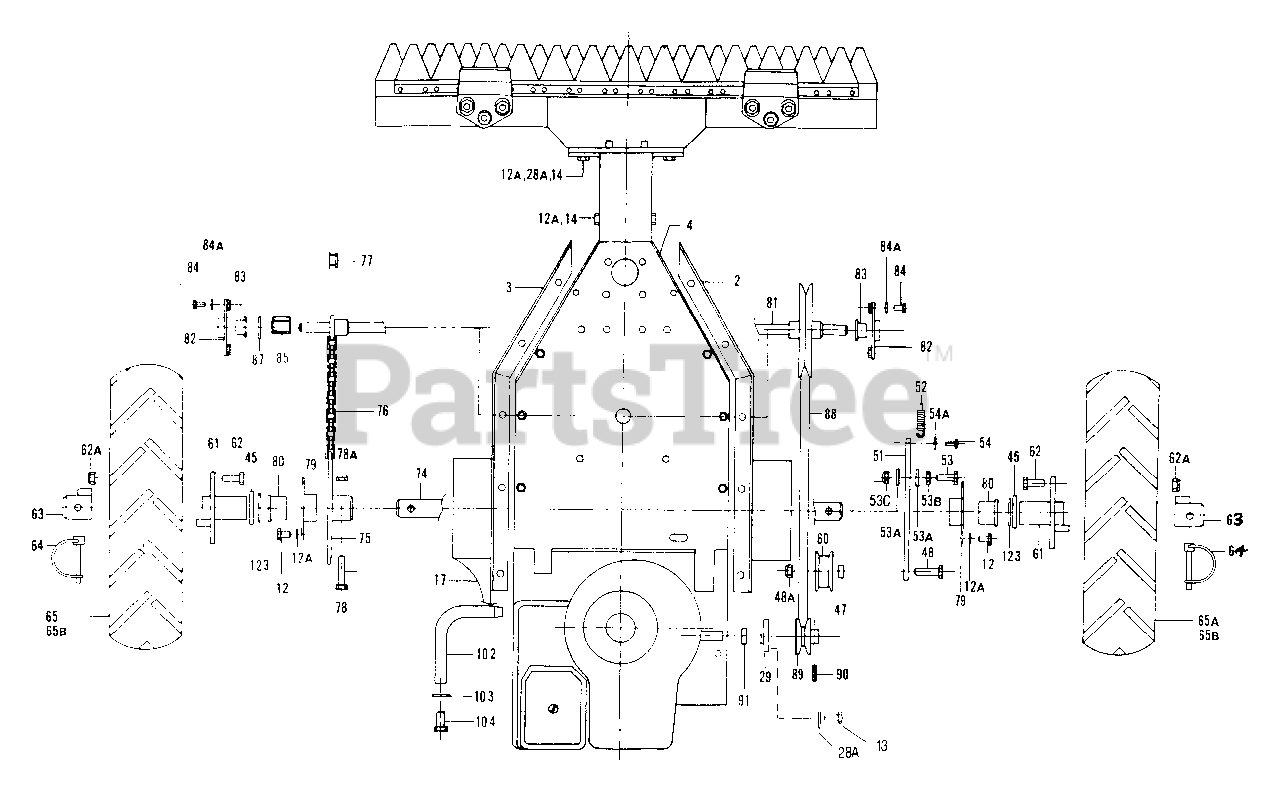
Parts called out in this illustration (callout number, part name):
2	Frame Plate-Right
3	Frame Plate-Left
4	Frame Plate-Bottom
12	Screw-HHM8 x 12
12A	Washer
13	Screw-HHM8 x 16
14	Screw-HHM8 x 16 Grade 10.9
17	Grass Shield-Wheel-LH
28A	Washer
29	Belt Guide
45	Snap Ring
47	Spacer - Pulley
48	Screw - HHM12 x 40
48A	Nylon Nut
51	Clutch Plate
52	Spring - Clutch Plate
53	Screw - HHM10 x 35
53B	Nut - HM10
53C	Nut - Nylon - HM10
54	Screw-HHM5 x 10
54A	Washer
61	Wheel Hub - 2 piece welded
62A	Lug Nut
63	Three-way Hub Lock
64	Retaining Clip (9377)
65	Wheel and Tire LH
65A	Wheel and Tire RH
75	Sprocket-Wheel Axle
76	Chain & Master Link
77	Master Link
78	Screw-HHM8 x 45
78A	Nylon Nut
79	Flange w/Bushing-Axle
80	Bushing-Wheel Axle
81	Jack Shaft Kit
82	Flange-Bearing Shaft
83	Bushing-Shaft
84	Screw-HHM6 x 12
84A	Washer
85	Spacer-Flange
86	Screw-HHM6 x 25
88	V-Belt-Wheel Drive
89	Pulley-Eng. Driven
90	Roll Pin
91	Washer-Felt
102	Tube-Oil Drain
103	Washer-Copper
104	Screw-HHM12 x 18
122	Spring-Cable-Wheel Drive
123	Washer-Wheel
